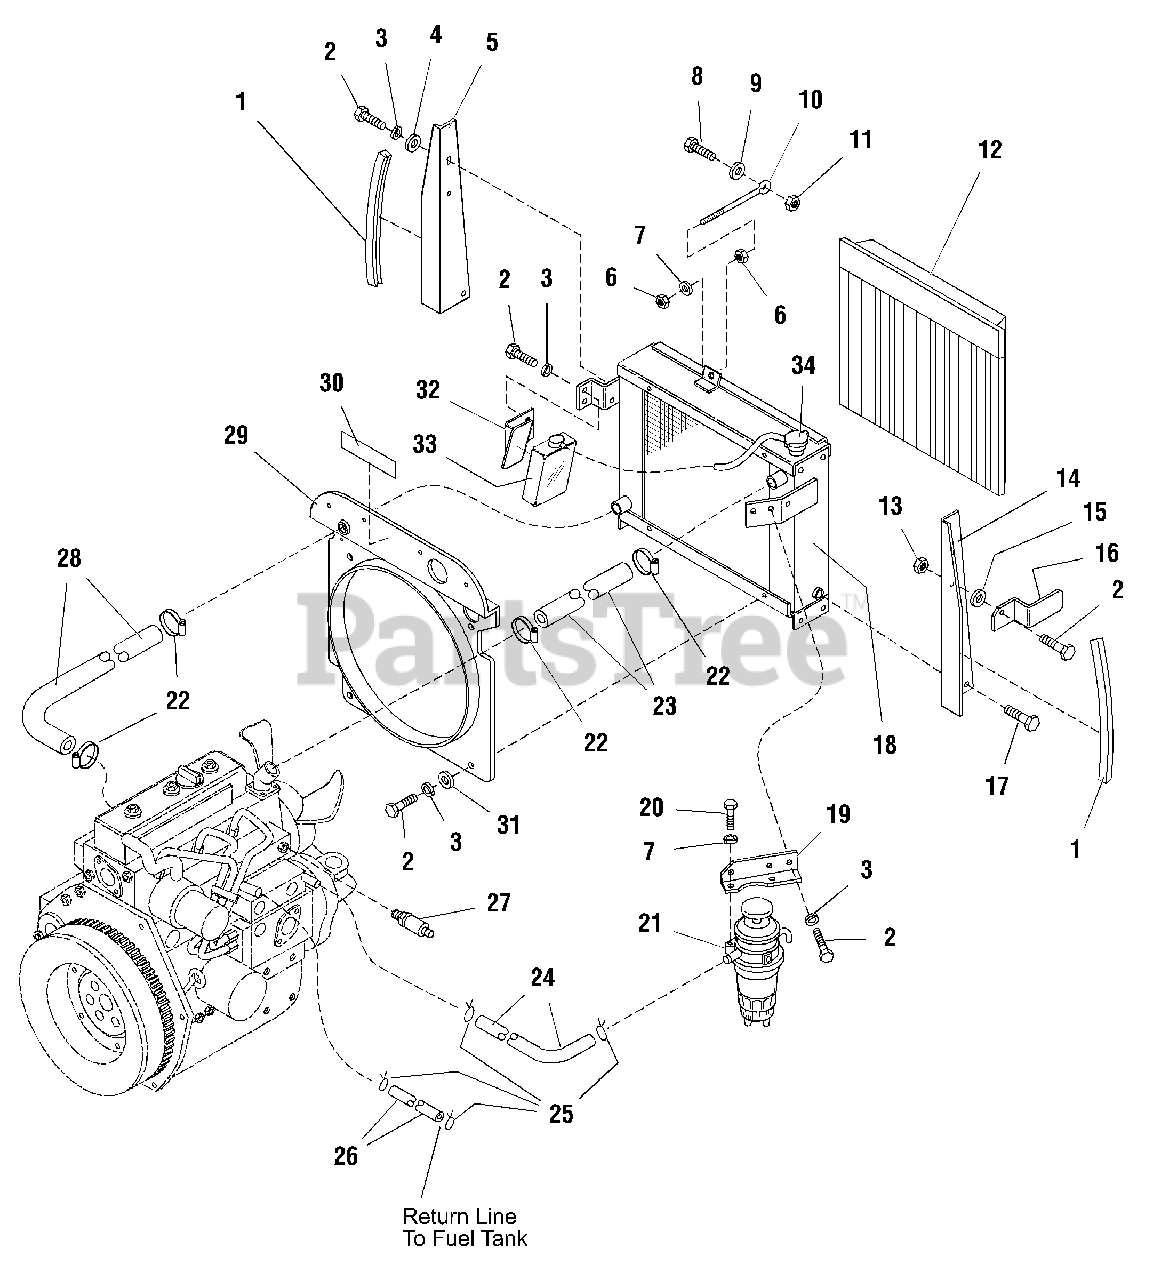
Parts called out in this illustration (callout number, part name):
1	EDGING, Side
2	CAPSCREW, Hex Hd, 1/4-20 x 3/4
3	LOCKWASHER, 1/4
4	WASHER, Plain, 1/4
6	NUT, Hex, Full, 5/16-18
7	LOCKWASHER, 5/16
8	CAPSCREW, Hex Hd, 1/8-16 x 1
9	WASHER, Plain, 3/8
10	ROD, Radiator
11	NUT, Hex, Nylon Lock, 3/8-16
12	SCREEN ASSY
13	NUT, Hex, Nylon Lock, 1/4-20
15	WASHER, Plain, 1/4
16	LATCH, Door
17	CAPSCREW, Hex Hd, Taptite, 5/16-18 x 1/2
18	RADIATOR ASSY
19	BRACKET, Fuel Filter
20	CAPSCREW, M8-1.25 x 20
21	FUEL FILTER ASSY.
22	CLAMP, Hose
23	HOSE, Engine Inlet
24	HOSE, Filter to Engine
25	CLAMP, Hose
26	HOSE, Engine to Tank
27	SENDER, Temperature
28	HOSE, Engine Return
29	SHROUD, Fan
30	DECAL, Radiator
31	WASHER, Flat, 1/4
32	BRACKET ASSY, Overflow
33	RESERVOIR, Coolant
34	CAP, Radiator
